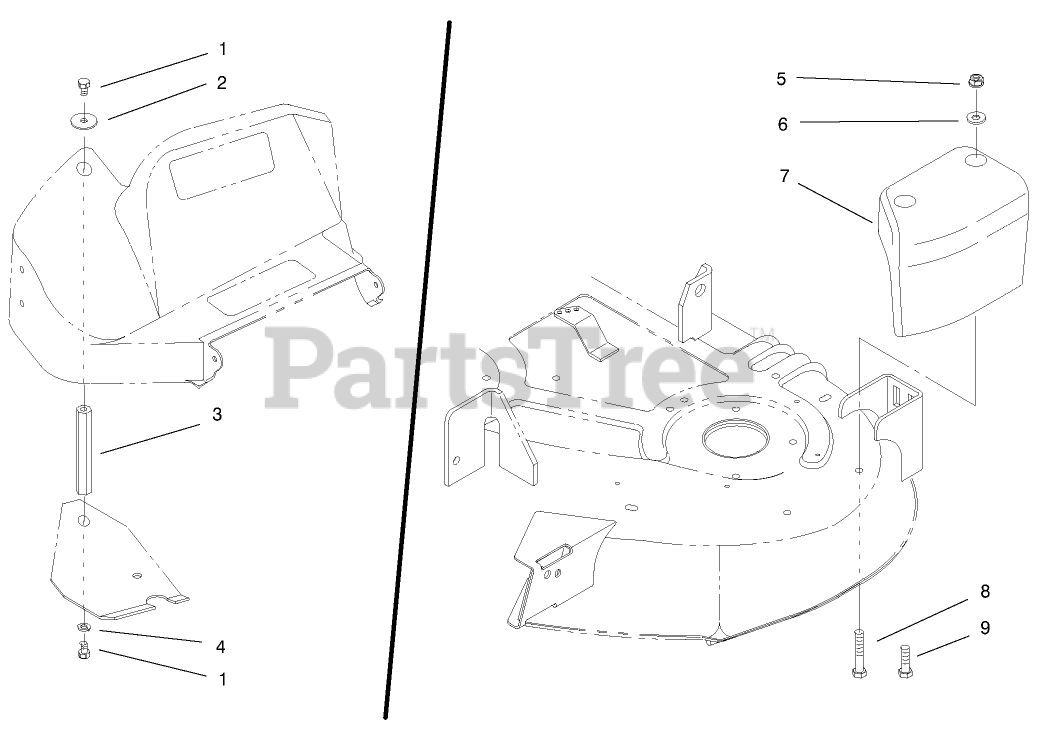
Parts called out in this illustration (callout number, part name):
1	SCREW-HH
2	WASHER-FLAT
3	SHAFT - VAC BAGGER
4	WASHER-LOCK
5	NUT-LOCK, NI
6	WASHER-FLAT
7	WEIGHT
8	SCREW-HH
9	SCREW-HH
